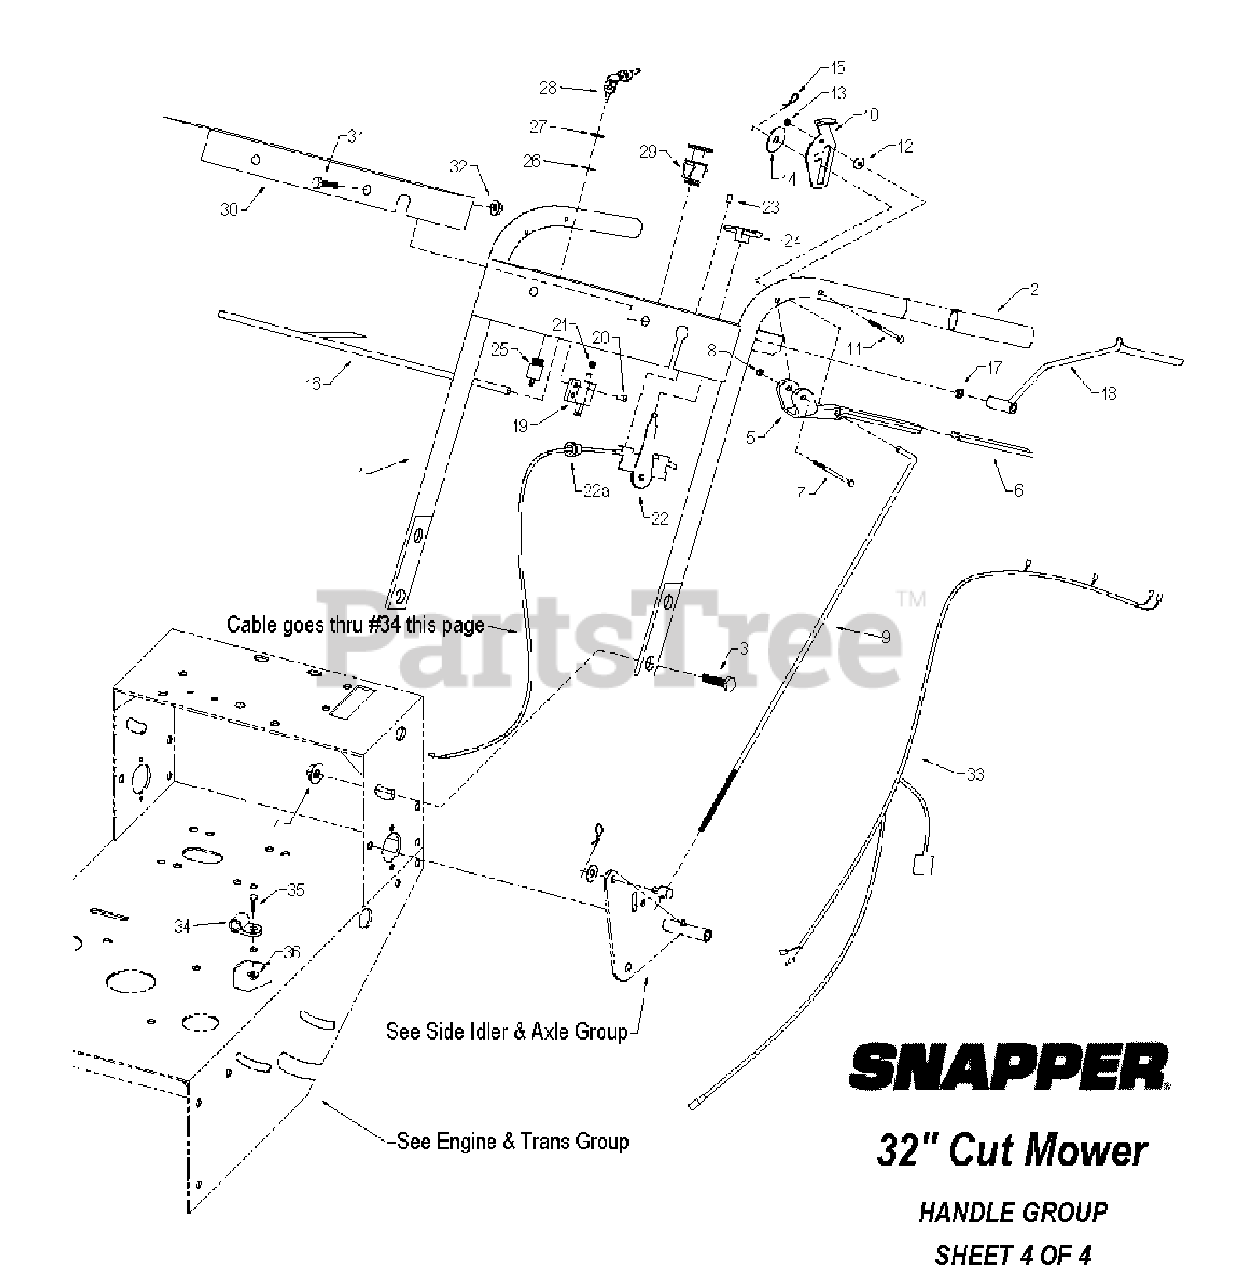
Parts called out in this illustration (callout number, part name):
1	Handle assembly
2	Handle grip - 1" dia x 4-1/2"
3	1/2-13 x 1-1/4" hex bolt
4	1/2-13 serrated flange nut
5	Brake handle
6	Handle grip - 1/4" x 3/4" x 4"
7	1/4-20 x 2" hex bolt
8	1/4-20 lock nut
9	Upper brake rod
10	Brake lock - left
11	1/4-20 x 1-1/2" hex bolt
12	1/4" spring washer
13	1/4-20 lock nut
14	5/16" fender washer
15	#1 bridge pin
16	Safety switch rod
17	3/8" I.D. flange bushing
18	Safety handle - left
19	Handle safety switch
20	3/16" pop rivet
21	Safety switch spring
22	Throttle control
23	Pop rivet
24	Throttle T-handle
25	Off switch
26	5/8" star washer
27	5/8-18 jam nut
28	Key set (set of 2)
29	PTO switch
30	Safety instruction decal bracket
31	5/16-18 x 3/4" hex bolt
32	5/16-18 small serrated flange nut
33	Wiring harness
34	Cable clip
35	1/4-20 x 5/8" hex bolt
36	1/4-20 serrated flange nut
